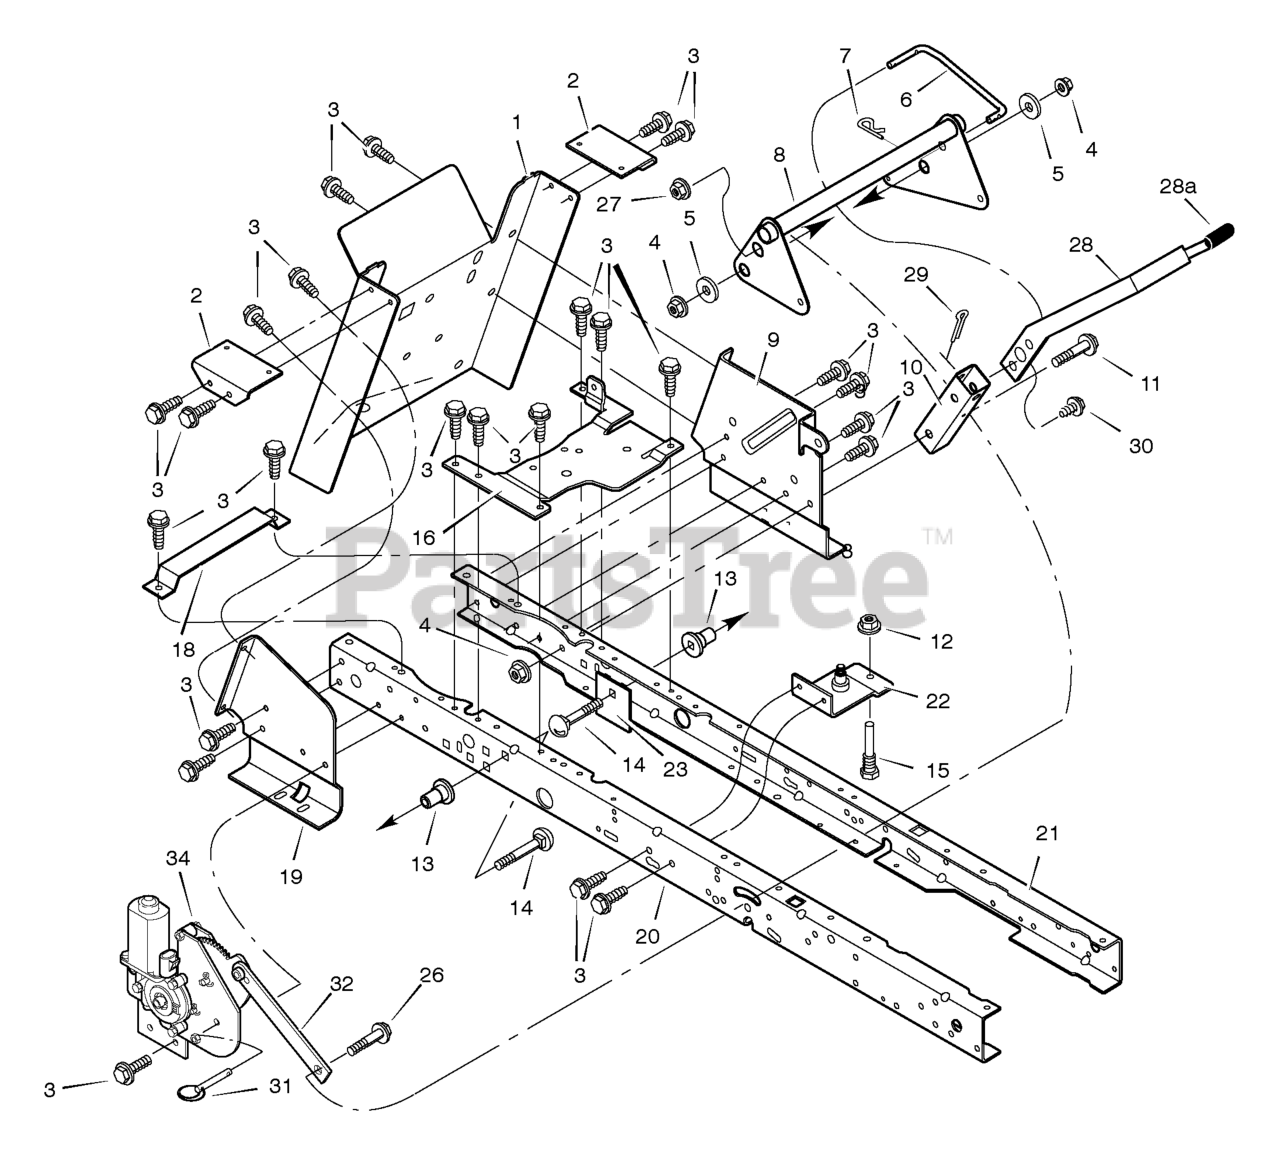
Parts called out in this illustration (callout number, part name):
1	Frame, Rear Hitch
2	Bracket, Seat Deck
4	Nut, Flange
6	Link, Lift Handle
7	Pin, Hair
8	Assembly, Lifter
9	Bracket, Left Transaxle
10	Bracket, Lift Pivot
11	Bolt, Shoulder
12	Nut
13	Spacer, Lifter
14	Bolt, Carriage
15	Guide, Belt
16	Bracket, Stationary Idler
19	Bracket, Right Transaxle
20	Frame, Right
21	Frame, Left
22	Bracket, Idler
23	Plate, Stiffening
26	Bolt, Shoulder
27	Nut, Flange
28	Indicator, Electric Lift
28A	Grip, Electric Lift
29	Pin, Cotter
30	Screw
31	Pin, Stop
32	Link, Bar
34	Ass'y, Gear Case & Motor
